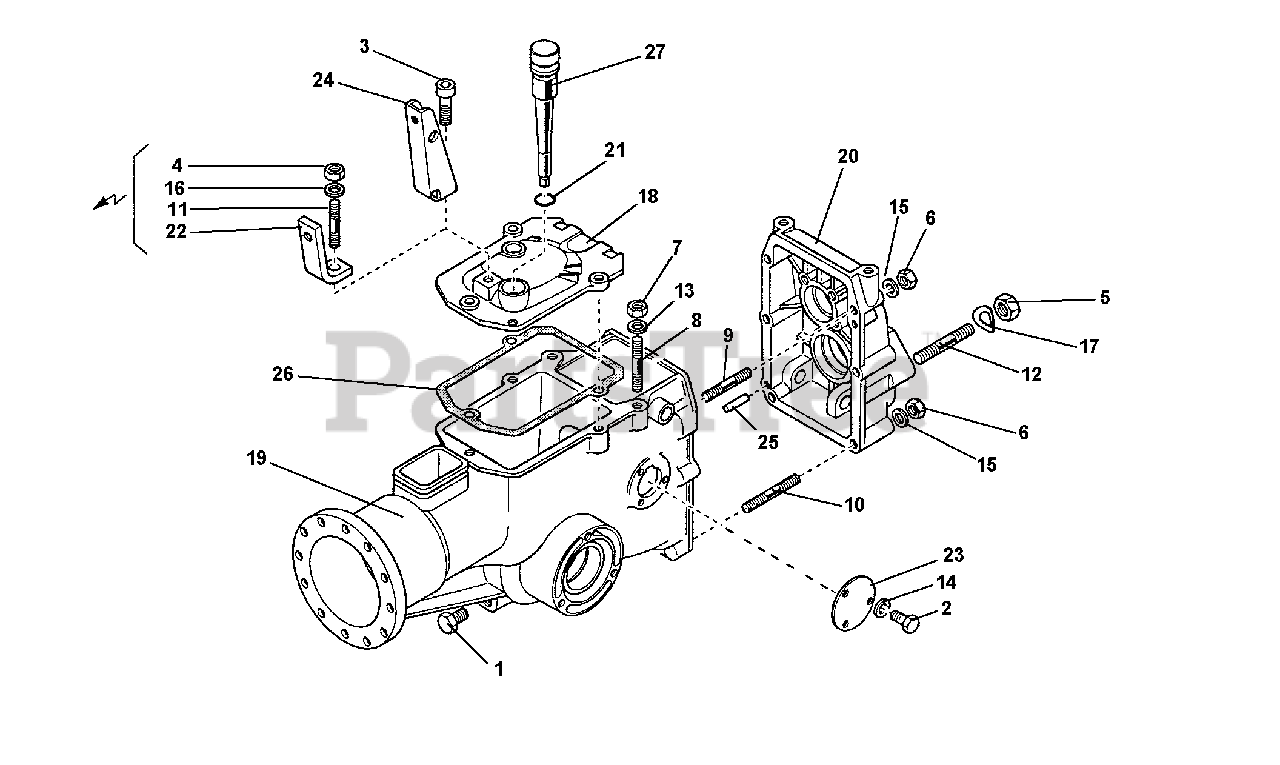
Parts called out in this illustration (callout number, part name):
2	SCREW M6X10
3	SCREW M10X25
5	NUT, M12X1.25
6	NUT, SELF LOCKING M8
8	STUD M8X38X14X20
9	STUD M8X58X16X16
11	STUD M10X37
12	STUD M12X1.25X12X52
13	SUPER WASHER 8
14	WASHER, LOCK 6.4
15	WASHER, LOCK 8.4
16	WAHSER M10.4
17	WASHER, LOCK, M13
18	GEARBOX COVER
19	GEAR BOX CASE
22	CLUTCH BRACKET
24	CLUTCH BRACKET
25	PARALLEL PIN
26	GASKET, COVER
27	CAP WITH DIP STICK
